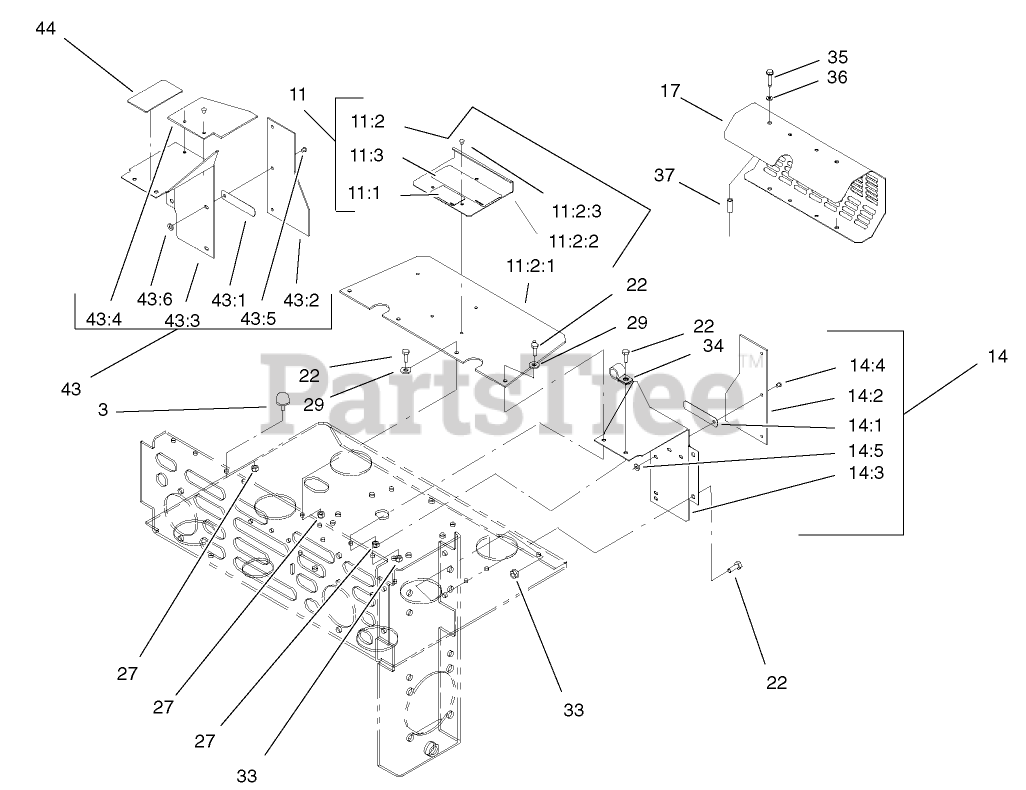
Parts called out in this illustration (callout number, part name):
3	BUMPER
11	SHIELD ASM
11:1	DECAL-IMPORTANT
11:2	SHIELD AND LIFT ASM
11:2:1	SHIELD-ENGINE
11:2:2	LIFT-SHIELD
11:2:3	RIVET-POP
11:3	DECAL-DEVICES, ROTATING
14	LH SHIELD ASM
14:1	CLIP-BAFFLE, REAR
14:2	SHIELD-ENGINE
14:3	BAFFLE-ENGINE SHIELD, LH
14:4	RIVET-POP
14:5	WASHER-FLAT
17	GUARD-MUFFLER
22	SCREW-HH
27	NUT-LOCK, NI
29	WASHER-FLAT
33	NUT-HF
34	CLIP-LOOM
36	WASHER-SPRING
37	SPACER
43	RH SHIELD ASM
43:1	CLIP-BAFFLE, REAR
43:2	SHIELD-ENGINE
43:3	SHIELD-RH
43:4	BAFFLE-COOLER, ENGINE
43:5	RIVET-POP
43:6	WASHER-FLAT
44	DECAL-ROUTING, BELT
